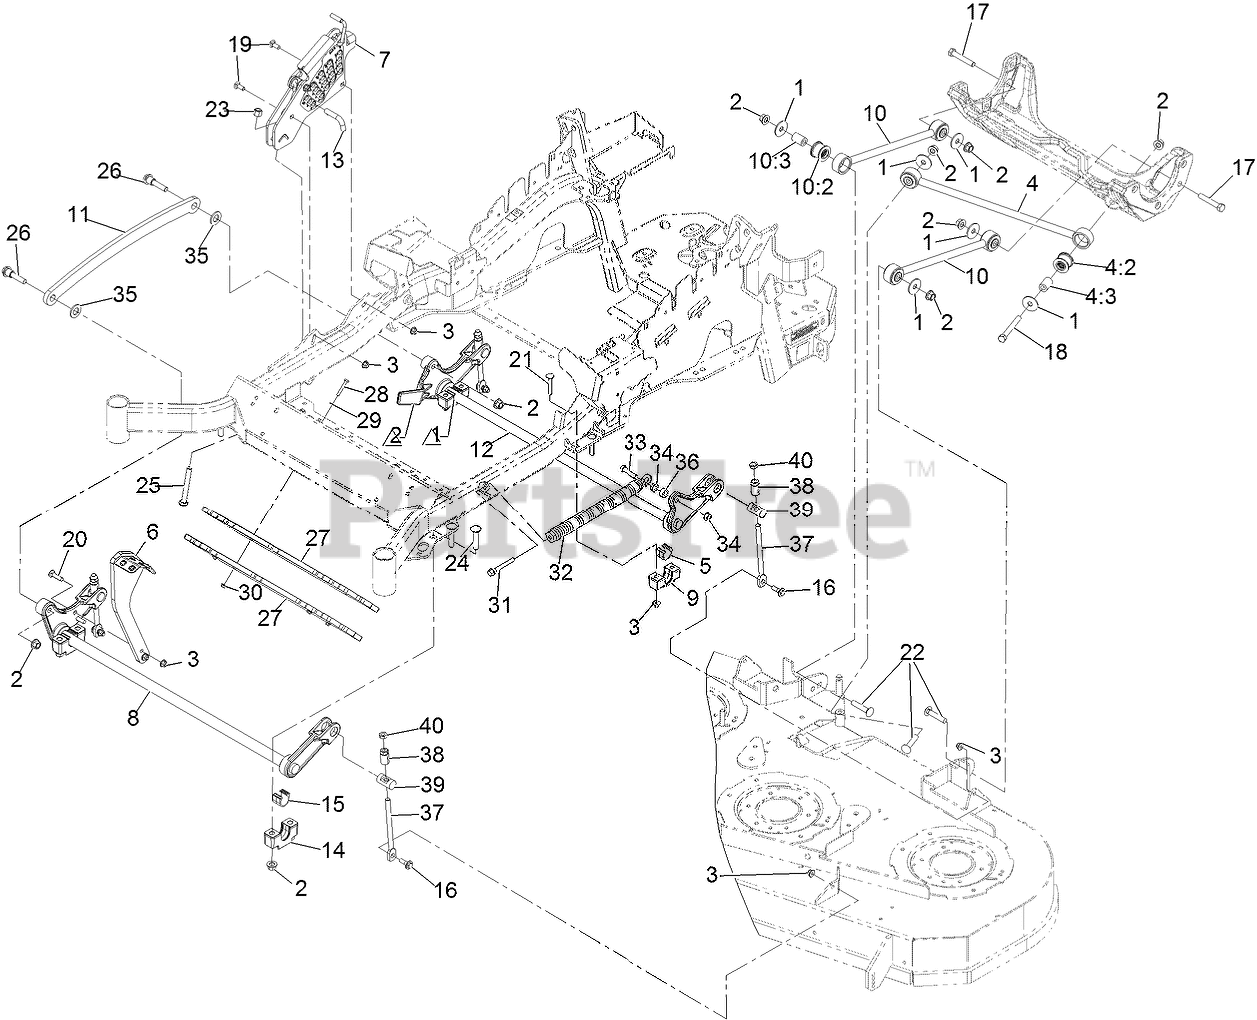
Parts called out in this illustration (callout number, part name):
1	WASHER-THRUST
2	Nut-Lock 1/2-13
3	NUT-HF, NI
4	PANHARD ROD ASM
4:2	BUSHING-SUSPENSION, RUBBER
5	BEARING-CROSS SHAFT, REAR
6	LEVER-FOOT
7	HOC ASM
8	DECKLIFT-FRONT
9	SUPPORT-CROSS SHAFT, BEARING REAR
10	DECK STRUT ASM
10:2	BUSHING-SUSPENSION, RUBBER
11	LINK-LIFT, DECK
12	LIFT-DECK, REAR
13	PIN-HOC
14	SUPPORT-CROSS SHAFT, BEARING
15	BEARING-CROSS SHAFT, FRON
16	SCREW-SHOULDER, HHF
17	SCREW-HH
18	SCREW-HH
19	BOLT-CARR
20	SCREW-CARR
21	Bolt-Carriage 3/8-16 X 2 1/4
22	SCREW-CARR
23	NUT-LOCK, NI
24	Bolt-Carriage 1/2-13 X 2 1/2 Spl Neck
25	BOLT-TAP
26	SCREW-HHF, SHOULDER
27	Weight-Toe Board
28	SCREW-HH
29	WASHER-FLAT
31	BOLT-SHOULDER
32	SPRING-EXTENSION
33	SCREW-HH
35	WASHER-FLAT
37	LINK-ADJUSTER, DECK LIFT
38	ADJUSTER-LIFT, DECK
39	TRUNNION
40	NUT-JAM
